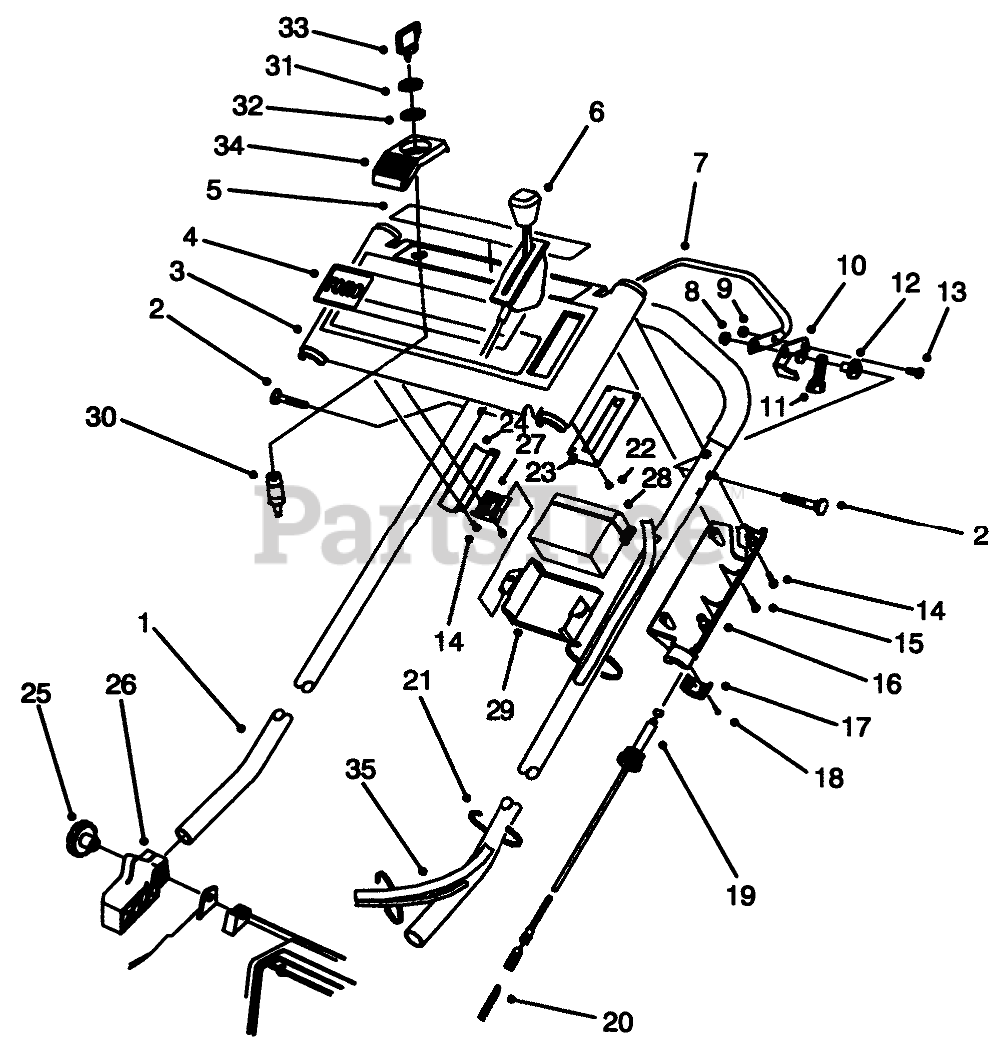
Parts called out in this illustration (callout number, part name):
1	Handle
2	SCREW-HANDLE
3	Panel-Control (Incl Ref. #4, & 5)
4	DECAL - PANEL KEY
5	DECAL - DANGER PANEL
6	THROTTLE CONTROL
7	CONTROL BAR
8	NUT-LOCK, NI
9	NUT-LOCK, NI
10	CONTROL LEVER
11	LEVER-TRACTION
12	SPACER-SUPPORT
13	SCREW-HH
14	SCREW-PPH, PLASTITE
15	Screw
16	Cover-Throttle Lower
17	LOWER THROTTLE CAP
18	#4-14X.62 PLASTITE SCW
19	TRACTION CABLE
20	SPRING-COMPRESSION
21	TIE-CABLE
22	#6-19X.25 PLASK FORM SC
23	THROTTLE PLATE
24	Bracket-Panel
26	MOUNT-HANDLE, RH
27	BATTERY BRACKET
28	Battery
29	BATTERY RETAINER
30	Switch-Starter (Incl. Ref. #31, & 32)
31	NUT-HH
32	WASHER-TOOTH, INTERNAL
33	KEY-IGNITION
34	IGNITION SWITCH BRACKET
35	Harness-Wire
